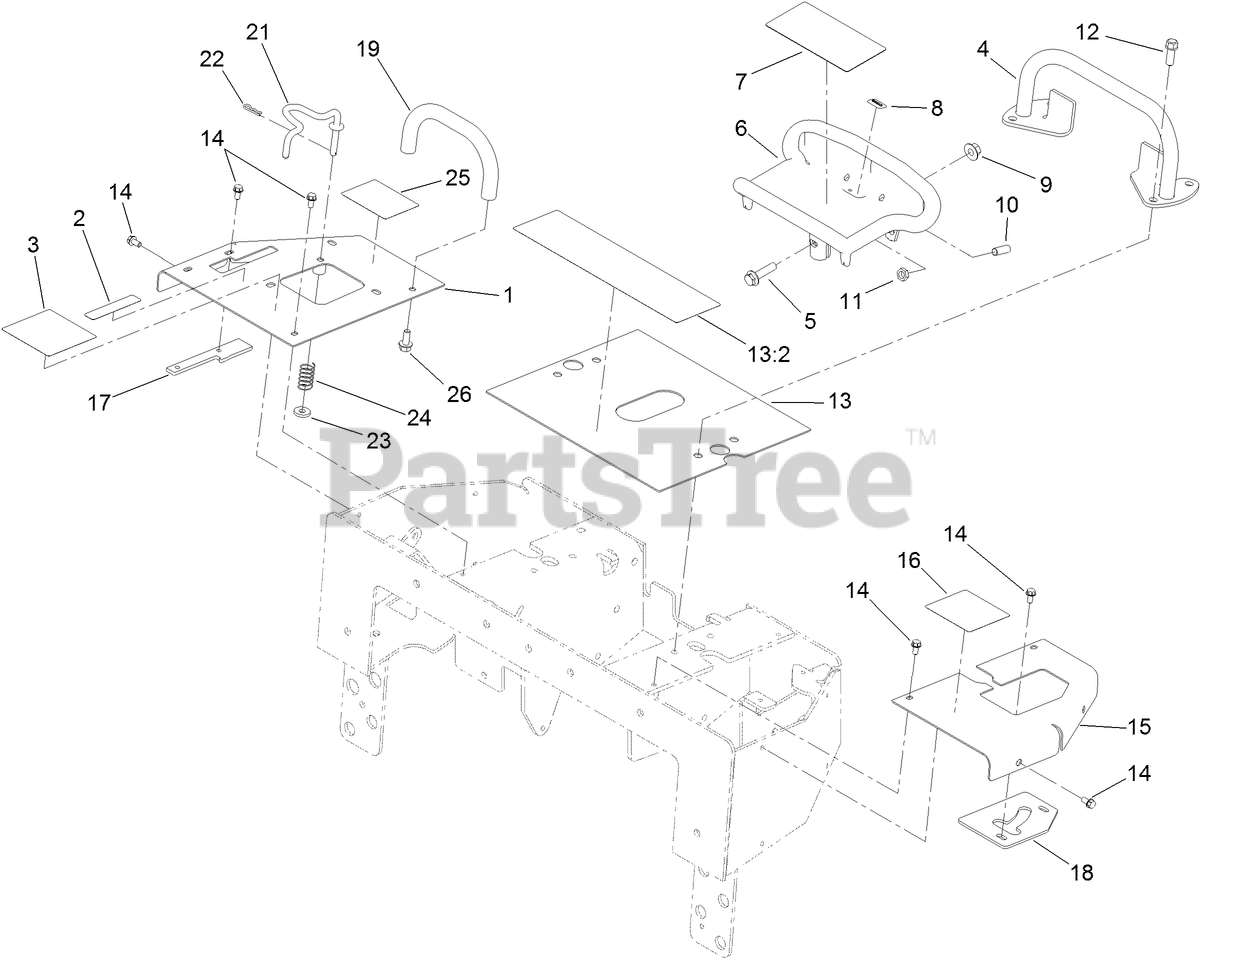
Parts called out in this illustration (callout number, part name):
1	PANEL-RH
2	DECAL-BRAKE
3	DECAL-CONTROL, LOADER
4	BAR-REFERENCE
5	SCREW-HHF
6	HANDLE-CONTROL
7	DECAL-TRACTION
8	DECAL
9	NUT-FLANGE
10	SCREW-SET
11	NUT-JAM
12	SCREW-TAPTITE
13	CENTER PANEL ASM
13:2	DECAL-DANGER
14	SCREW-HWH
15	PANEL-LH
16	DECAL-CONTROL, AUXILIARY
17	PLATE-LOCKING, BRAKE
18	PLATE-STOP
19	BAR-REFERENCE
21	ROD-INTERLOCK
23	WASHER-FLAT
24	SPRING-CONTROL
25	DECAL-LOADER LOCK
26	SCREW-HHF
